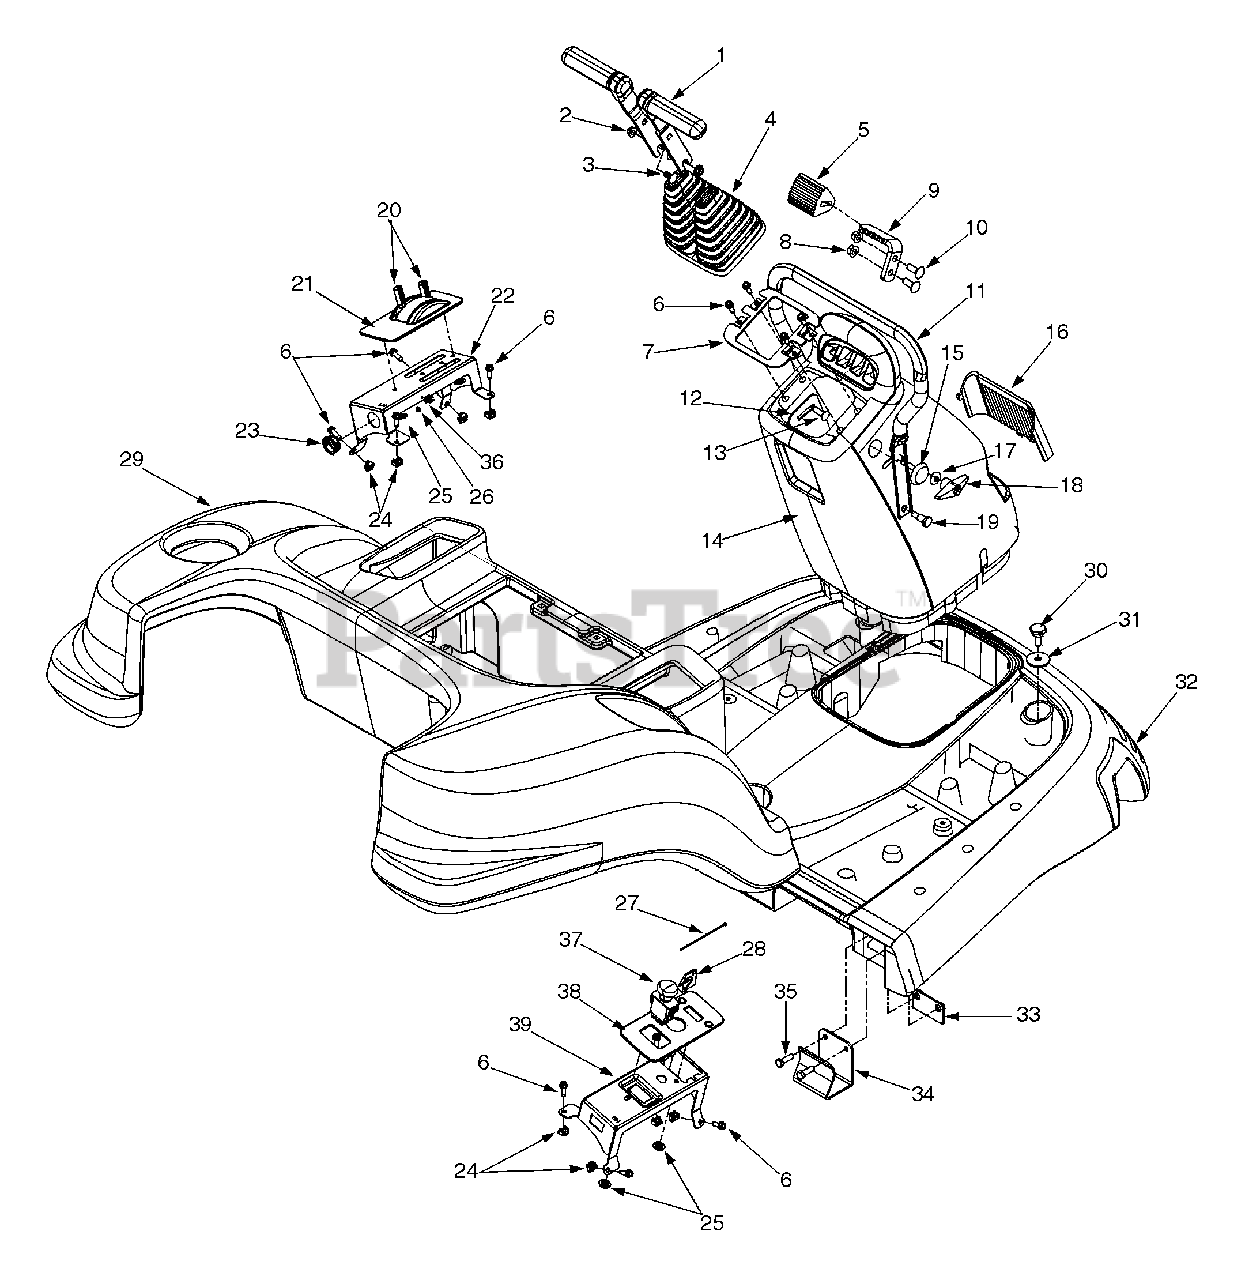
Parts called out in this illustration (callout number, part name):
1	Control Handle
2	Flange Lock Nut 5/16-18
3	Carriage Bolt 5/16-18
4	Bellow
5	Foot Pad
6	Hex Washer Screw 1/4-20 x .75
14	Console
17	Bell Washer .340 ID x .672 OD
18	Wingnut Knob
19	Shoulder Screw
20	Knob
21	LH Control Panel Cover
24	Retainer Nut 1/4-20
25	Push Nut
26	Pop Rivet
27	Cable Tie
29	Rear Body
30	Shoulder Screw 3/8-16
31	Flat Washer .406 ID x 1.5 OD
32	Floor Body
33	Body Plate Assembly
36	Spring Clip
37	Electric PTO Switch
38	RH Control Panel Cover
